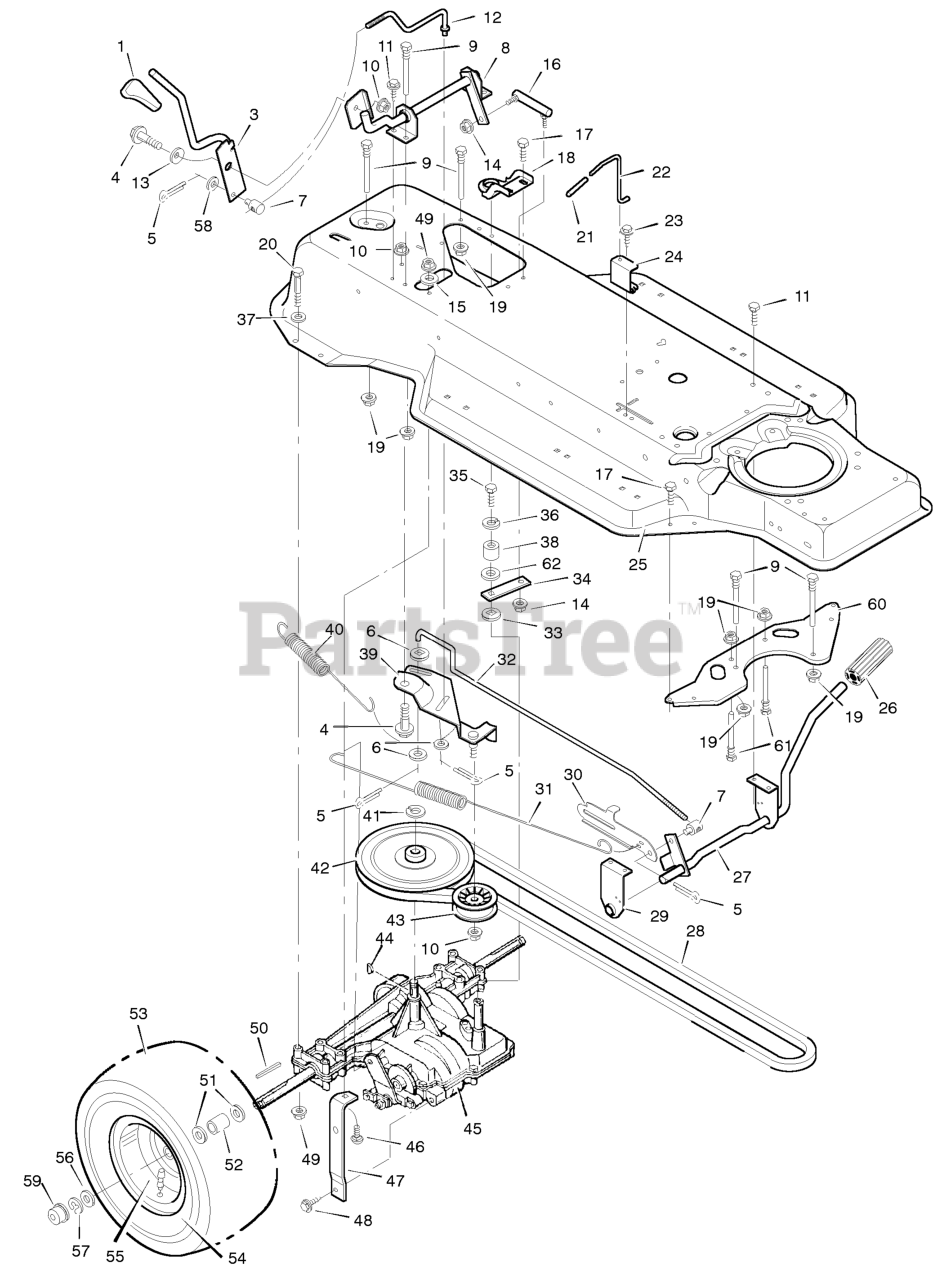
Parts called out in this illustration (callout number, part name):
1	Grip
3	Handle, Shift
4	Bolt, Shoulder
5	Pin, Cotter
6	Washer
7	Nut, Adjustable
8	Shifter Assembly
9	Guide, Belt
10	Locknut, Flange
12	Link, Clutch
13	Washer, Curved
14	Locknut, Flange
16	Link Assembly, Shifter
18	Bracket, Support
19	Nut, Flange
20	Bolt, Hex
22	Rod, Control
24	Guide, Bracket
25	Frame Assembly
26	Pedal, Clutch/Brake
27	Lever Assembly
28	Belt, Motion Drive
29	Bracket, Lever Support
30	Latch, Park Brake
31	Spring, Brake Extension
32	Rod, Clutch
34	Yoke, Shift
35	Bolt, Hex
36	Lockwasher
37	Washer
38	Pilot, Support
39	Bracket Assembly, Idler
40	Spring, Motion Drive
41	Ring, Retainer
42	Pulley, Motion Drive
43	Pulley, Backside Idler
44	Key, Woodruff
45	Transaxle, Peerless **
46	Bolt, Carriage
47	Support, Transaxle
49	Locknut, Flange
50	Key, Square
52	Spacer, Transaxle
53	Tire *
54	Wheel and Tire Assembly
55	Valve Stem
57	E- Ring
58	Washer
59	Hub Cap
60	Plate, Belt Guide
61	Guide, Belt
